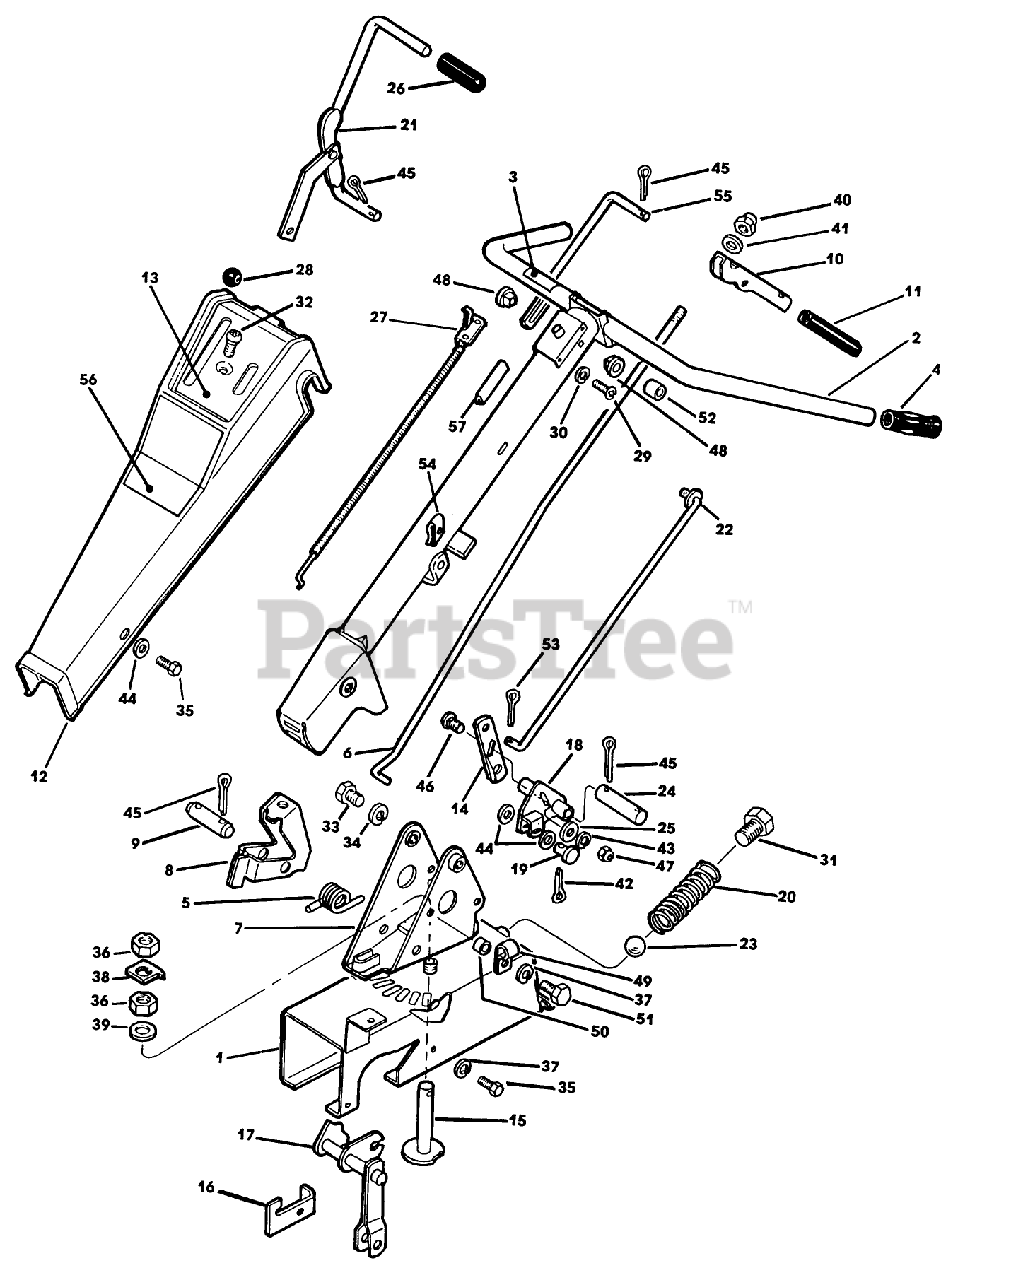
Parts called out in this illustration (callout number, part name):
6	CONTROL ROD
20	DETENT SPRING
27	THROTTLE CONTROL
34	WASHER
35	SCREW-HH
40	NUT-LOCKING
41	WASHER
47	NUT
51	SCREW
54	NUT-SPEED
